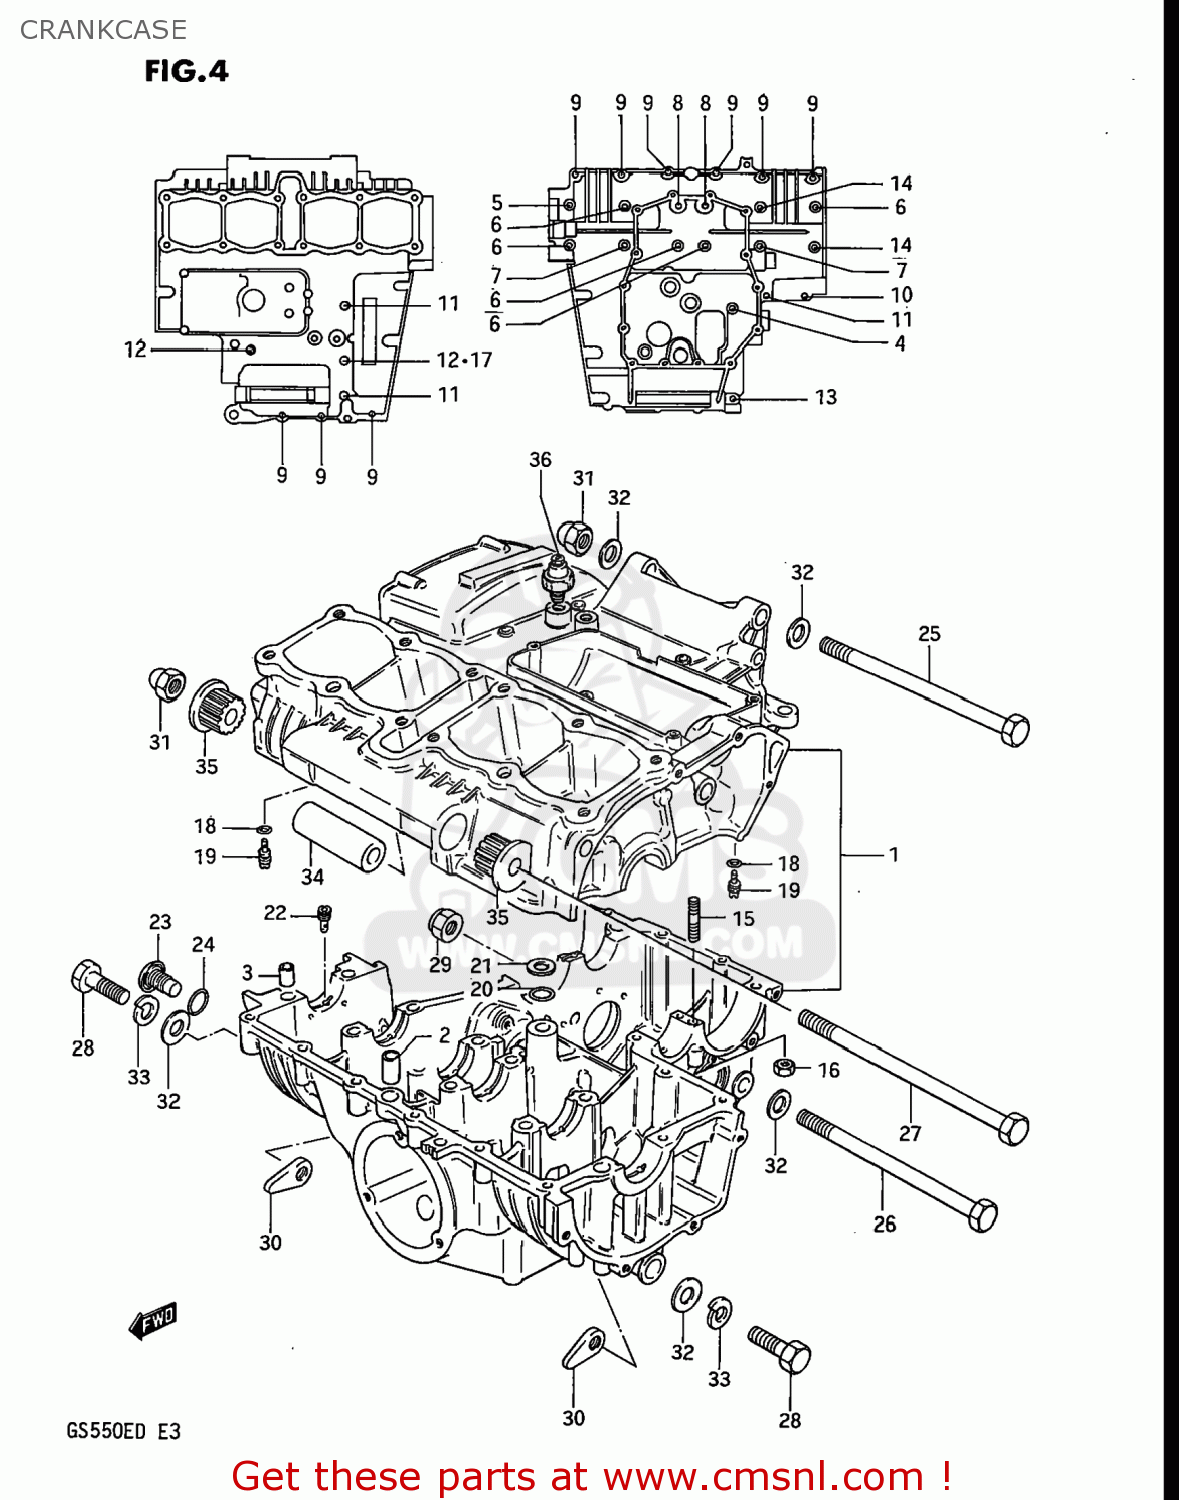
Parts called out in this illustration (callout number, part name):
1	CRANKCASE SET
2	PIN(10.4X13X22)
3	PIN (11X20)(SUS)
4	BOLT(6X100)
5	BOLT
6	BOLT
7	BOLT(8X120)
8	BOLT
9	BOLT
10	BOLT 6X55
11	BOLT
12	BOLT (5X95)
13	BOLT 8X60
14	BOLT (8X90)
15	STUD BOLT
16	NUT
17	GASKET(6.2X13X1.2) (NAS)
18	O RING(D:1.2,ID:4)
19	JET,OIL GALLERY
20	O RING(D:3.2,ID:12.9)
21	WASHER,THRUST
22	JET,AIR
23	PLUG
24	O RING(D:2.4,ID:16.8)
25	BOLT
26	BOLT
27	BOLT
28	BOLT
29	NUT 10MM
30	NUT
31	NUT
32	WASHER
33	LOCK WASHER
34	SPACER (10.2X16X105.5)
35	BUSH
36	SWITCH ASSEMBLY
